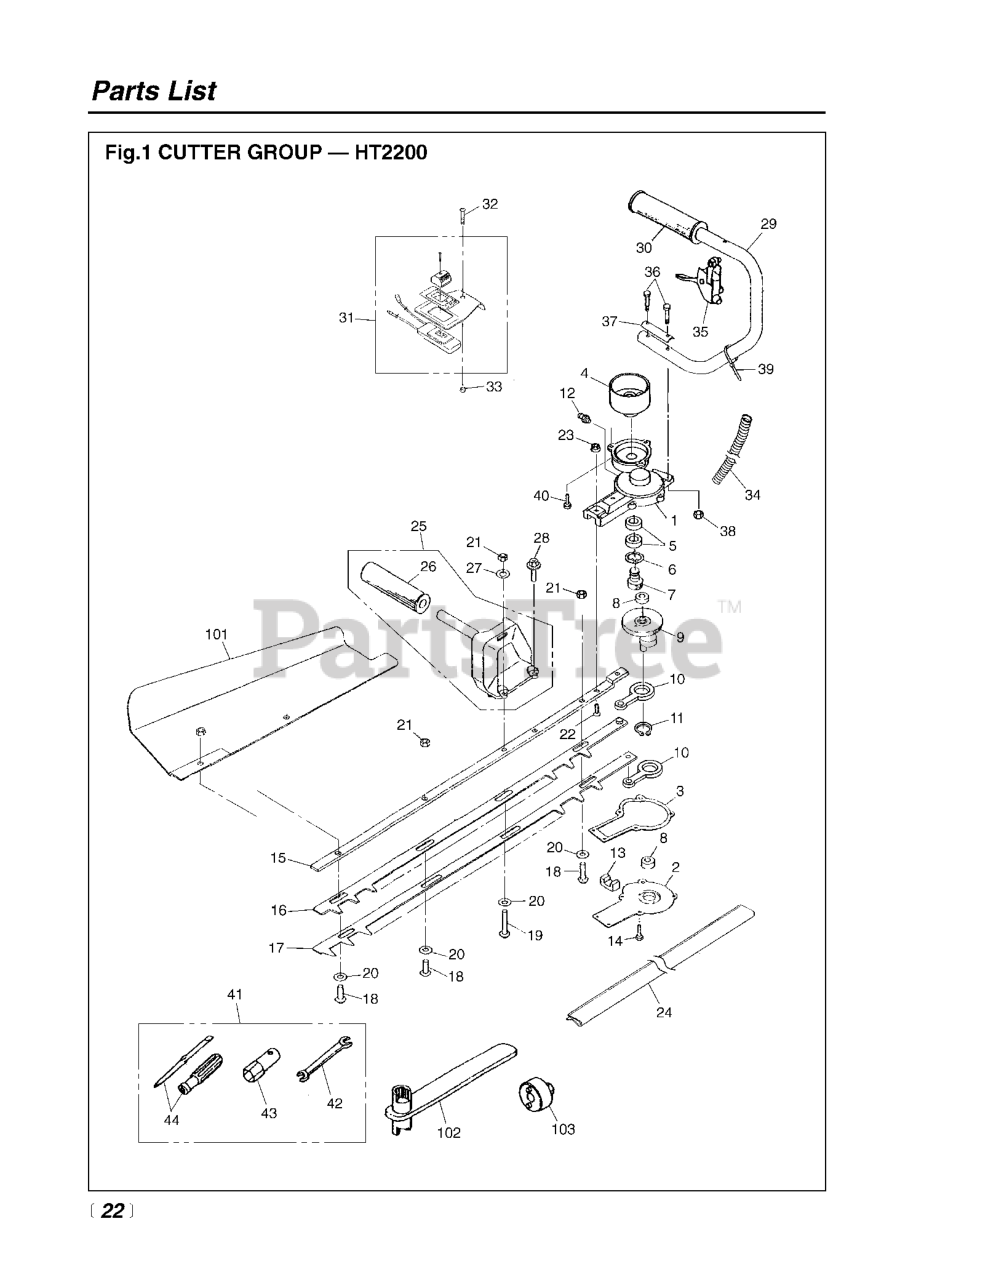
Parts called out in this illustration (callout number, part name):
1	GEARCASE
6	RING, SNAP
8	BEARING
9	GEAR COMPL
11	RING, SNAP, M25 x 1.2
14	BOLT (RPLS 020510512)
16	BLADE, UPPER
17	BLADE, LOWER
18	SCREW
24	COVER, BLADE
25	HANDLE (R)
29	HANDLE COMP.
35	LEVER ASSY
41	TOOL SET
101	RECEIVE PLATE
102	WRENCH(B)
